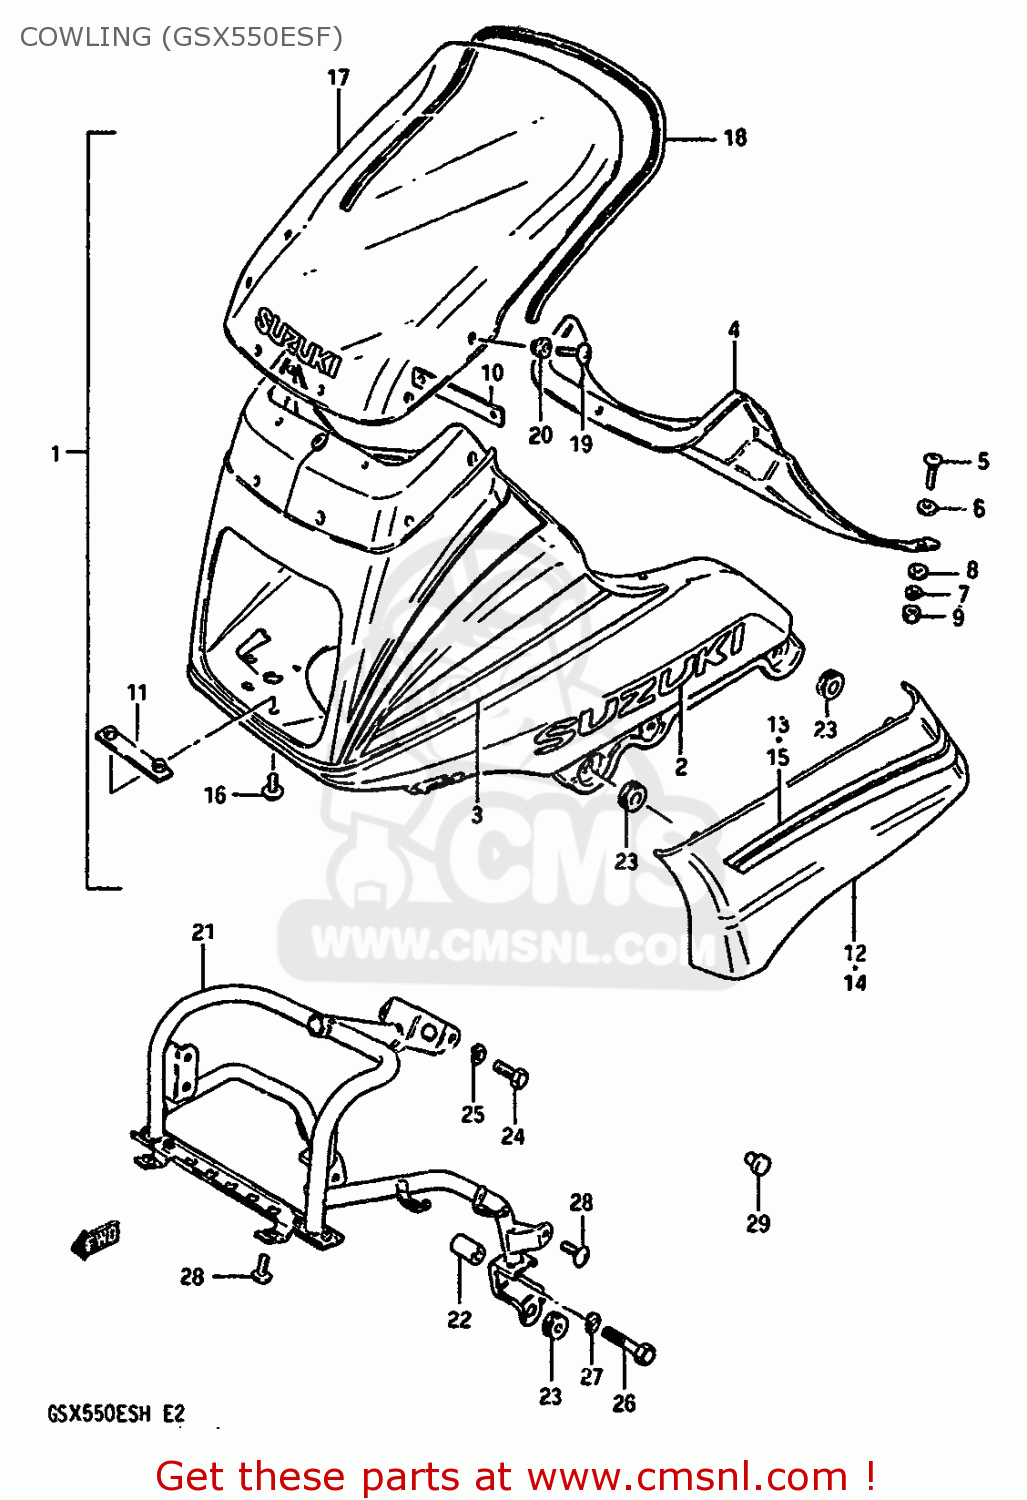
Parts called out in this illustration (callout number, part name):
1	COWLING ASSY (WHITE/RED)
2	EMBLEM
3	TAPE SET
4	PANEL,COWLING,UPPER
5	SCREW
6	WASHER,5MM
7	WASHER,LOCK
8	WASHER,5MM
9	NUT ,5MM
10	BRACKET,COWLING,UPPER
11	BRACKET,COWLING,LOWER
12	COVER,COWLING,RIGHT
13	TAPE SET
14	COVER,COWLING
15	TAPE SET
16	SCREW
17	WINDOW
18	MOLDING,LOWER
19	SCREW
20	CUSHION
21	BRACE,COWLING
22	SPACER (8.2X12.5X23.5)
23	CUSHION
24	BOLT
25	WASHER,LOCK,8.
26	BOLT
27	WASHER,LOCK,8.
28	SCREW 6X12
29	PLUG
